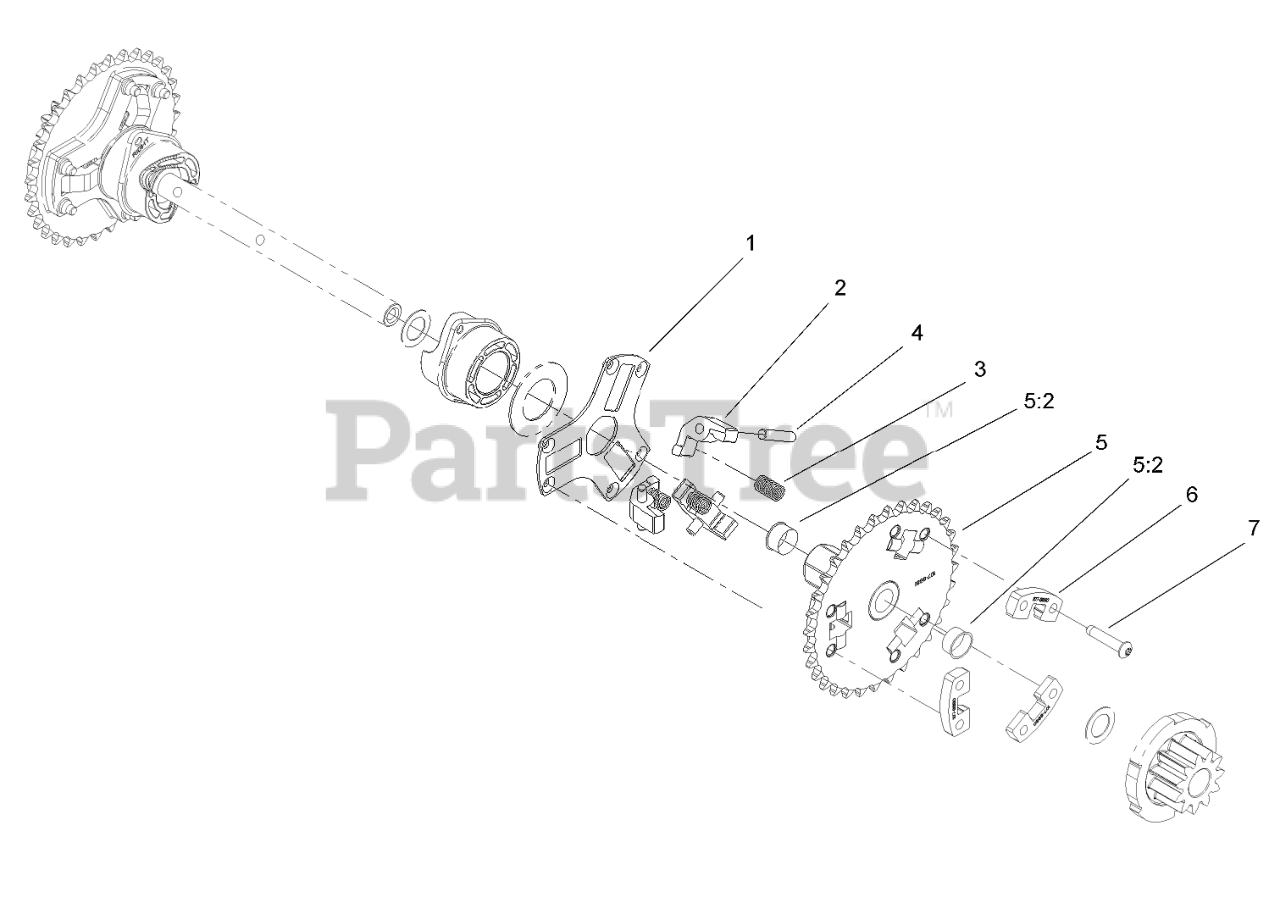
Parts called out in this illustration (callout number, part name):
1	RETAINER-PIN, PAWL
2	PAWL-CLUTCH
3	SPRING-COMPRESSION
4	PIN-DOWEL
5	32T SPROCKET ASM
5:2	BUSHING-FLANGE
6	SUPPORT-PAWL
7	SCREW-TTH, THREAD ROLLING
